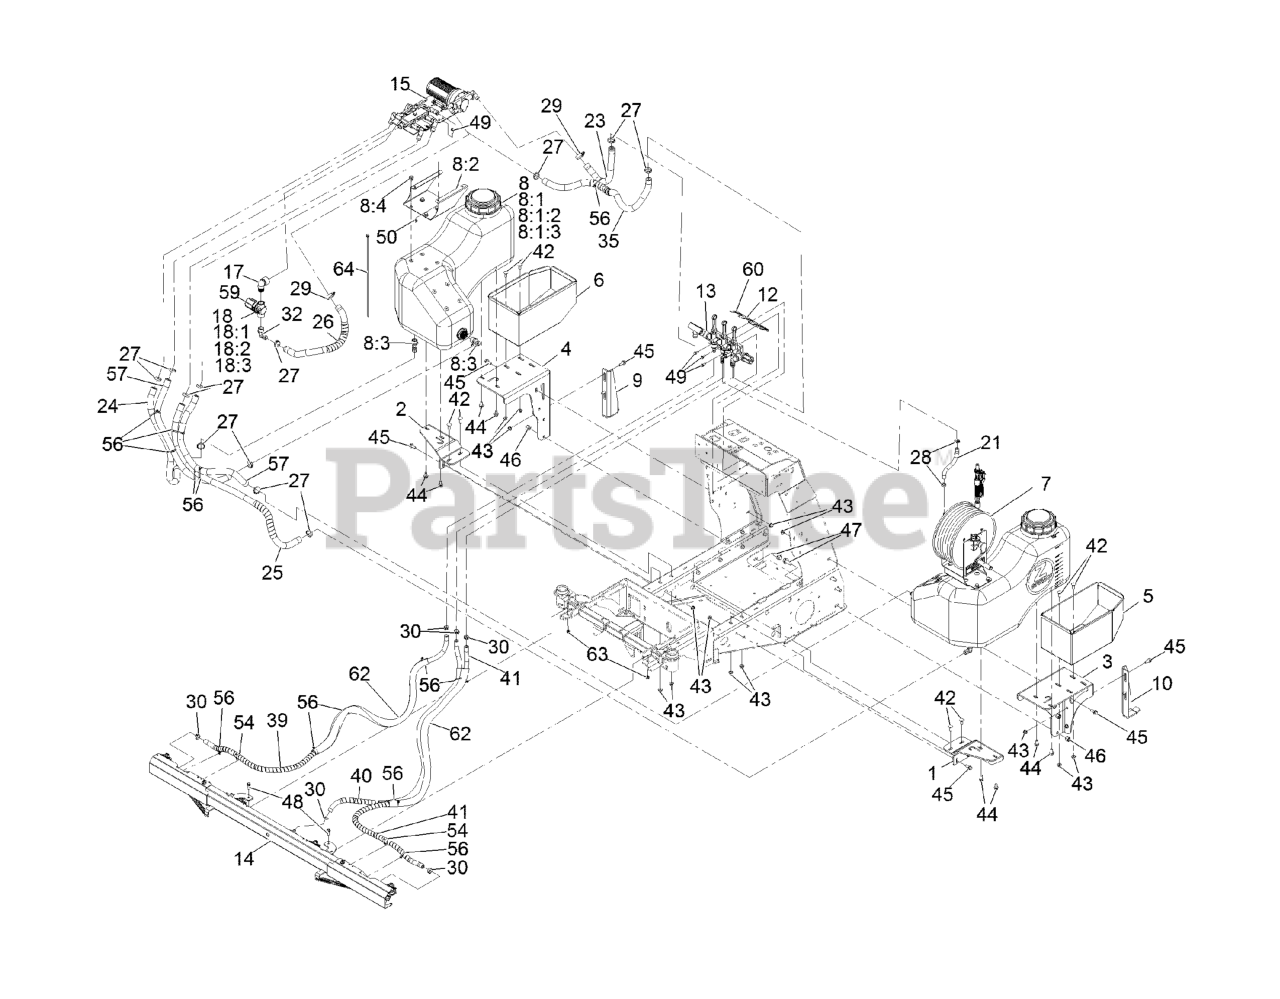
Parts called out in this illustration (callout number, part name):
1	Mount-Tank, LH Wing
2	Mount-Tank, RH Wing
3	Mount-Box, Lt Fert
4	Mount-Box, Rt Fert
5	BOX-FERT, LT
6	Box-Fert, Rt
7	ASM-Tank, Hose Reel
8	ASM-Tank, Rt
8:1	ASM-TANK, RT
8:1:2	CAP-TANK, SPRAY
8:1:3	FITTING-BULKHEAD
8:2	FITTING-ELBOW, 90
8:3	PLATFORM, LIQUID VALVE MO
8:4	Screw-HHF
9	Bracket-Anti-Tip, Rt
10	Bracket-Anti-Tip, Lt
12	BRACKET-MANIFOLD
13	ASM-Manifold
14	ASM, Boom
15	ASM, Liquid Valve
17	ELBOW-90DEG
18	STRAINER-INLINE
18:1	BOWL-STRAINER
18:2	GASKET-HEAD, LINE STRAINE
18:3	Screen-Strainer, 50 Mesh
21	Hose-Spray
23	Hose-Spray
24	Hose-Spray
25	Hose-Spray, Wrapped
26	Hose-Spray, Wrapped
27	Clamp-Oetiker, 167
28	CLAMP-OETIKER, 167
29	CLAMP-HOSE
30	CLAMP-OETIKER, 167
32	FITTING-ELBOW, 90
35	Hose-Spray, Wrapped
39	Hose-Spray, Wrapped
40	Hose-Spray, Wrapped
41	Hose-Spray, Wrapped
42	SCREW-CARR
43	Nut-Hex Flange
44	SCREW-HHF
45	SCREW-HHF
46	Nut,1/2-13,NYL INS,ST/ST,18-8
47	SCREW-HHF
48	SCREW-HHF
49	Screw-HHF
50	Nut-Hex Flange
54	CLIP-TIE
56	TIE-CABLE
57	Hose-Spray
59	DECAL-CAP, STRAINER
60	Decal-Valve, Boom
62	Guard-Mesh
63	Nut-Hex Flange
64	TIE-CABLE
